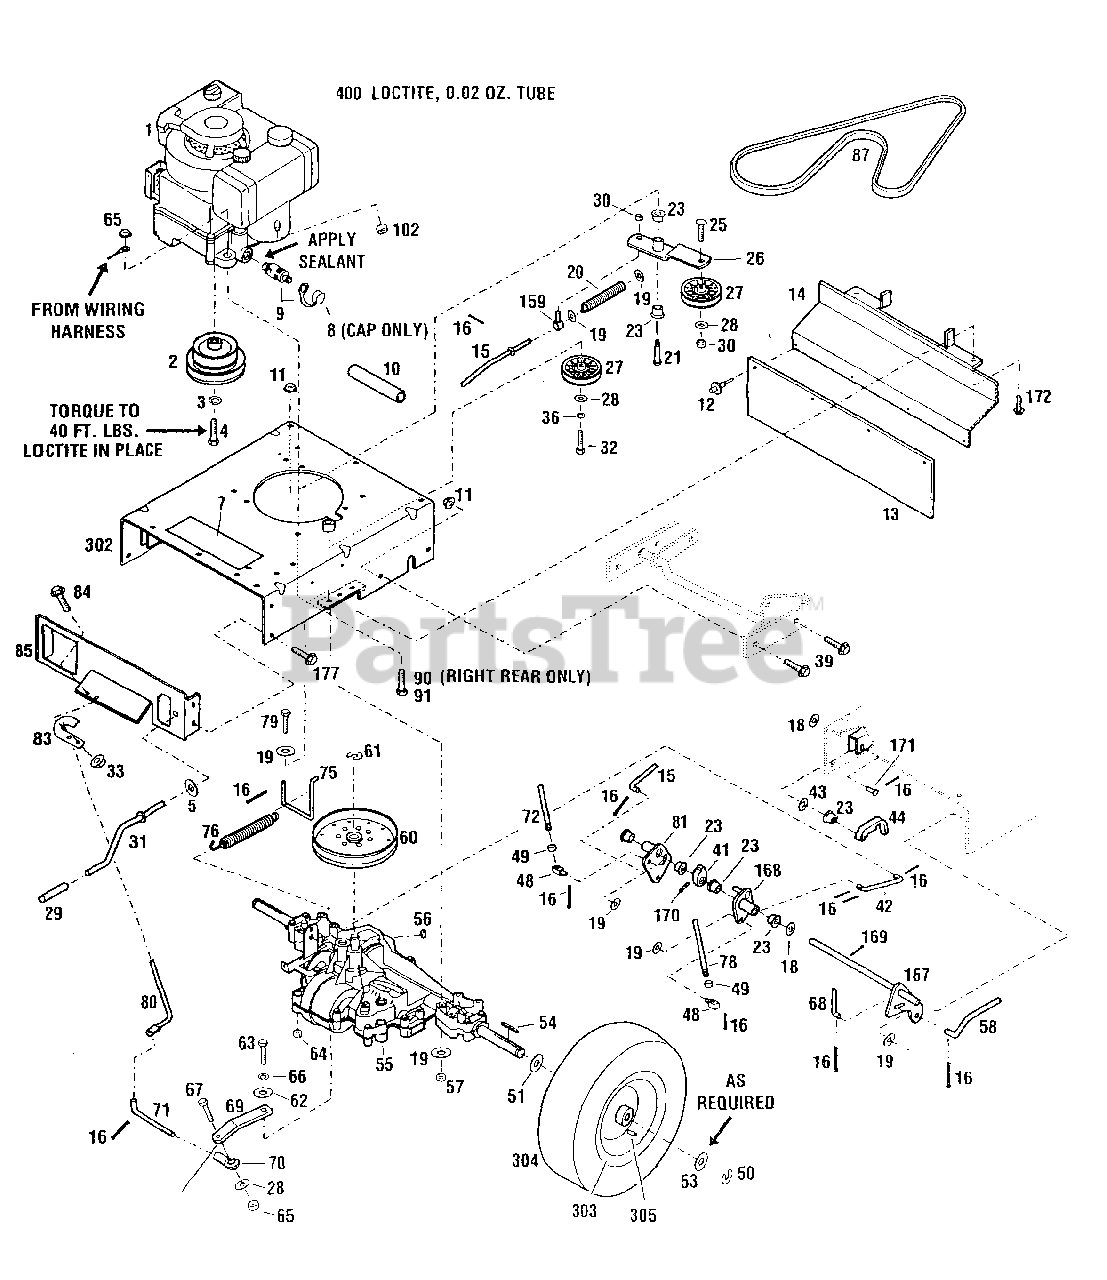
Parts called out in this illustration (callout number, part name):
1	Engine - Electric Start
1	Engine - Recoil Start
2	Engine Pulley
3	Lock Washer, 7/16
4	Bolt, 7/16-20 x 1-3/4
5	Washer, Nylon
7	Warning Decal
8	Oil Valve Cap
9	Oil Valve
10	Oil Drain Hose
11	Flange Locknut, 3/8-16
12	Pop Rivet, 3/16
14	Flap Bracket
15	Lower Transmission Rod
16	Cotter Pin, 3/32 x 5/8
18	Flat Washer, 1/2
19	Flat Washer, 5/16
20	Compression Spring
21	Shoulder Bolt
23	Nyliner, 1/2
25	Carriage Bolt, 3/8-16 x 1-3/4
26	Idler Arm
27	Idler Pulley
28	Flat Washer, 3/8
29	Plastic Grip
30	Top Locknut, 3/8-16
31	Lift Crank Assembly
32	Bolt, 3/8-16 x 1-3/4
33	Flange Locknut, 1/4-20
36	Lock Washer, 3/8
39	Flange Lock Screw, 3/8-16 x 1
41	Interlock Cam
42	Lower Brake Rod
43	Washer, Flat 1/2
44	Interlock Latch
48	Swivel Block
49	Jam Nut, 5/16-18
50	Retaining Ring
51	Flat Washer
53	Special Washer
54	Square Key, 3/16 x 2-1/2
55	Transmission Assembly,
56	Woodruff Key, 3/16 x 3/4
57	Top Locknut, 5/16-18
58	Lower Blade Rod
60	Transaxle Pulley
61	Retaining Ring
62	Flat Washer, 1/4
63	Screw, 1/4-28 x 3/4
64	Flange Locknut, 5/16-18
65	Locknut, 3/8-16
66	Lock Washer, 114
67	Screw, 3/8 x 1-1/4
68	Upper Blade Rod
69	Transmission Arm
70	Ball Joint
71	Shift Link Rod
72	Upper Transmission Rod
75	Spring Attachment Rod
76	Extension Spring
78	Upper Brake Rod
79	Screw, 5/16-18 x 2-3/4
80	Shift Rod
81	Clutch Arm Pivot
83	Shift Rod Bracket
84	Flange Lock Screw, 1/4-20 x 1/2
85	Backplate
87	V-Belt
90	Thread Forming Screw, 3/8-16 x 1-1/2
91	Thread Forming Screw, 3/8-16 x 1
102	Hex Nut, 1/4-20
159	Eye Bolt
167	Pivot Shaft Assembly
168	Brake Arm
169	Cotter Pin
170	Drive Pin, 5/32 x 1
171	Clevis Pin, 1/2 x 1-1/4
172	Screw, 5/16-18 x 3/4
177	Flange Screw, 5/16-18 x 3/4
302	Frame Weldment Assy
303	Wheel Rim
305	Valve Stem
400	Loctite 242, 0.02 oz. Tube
